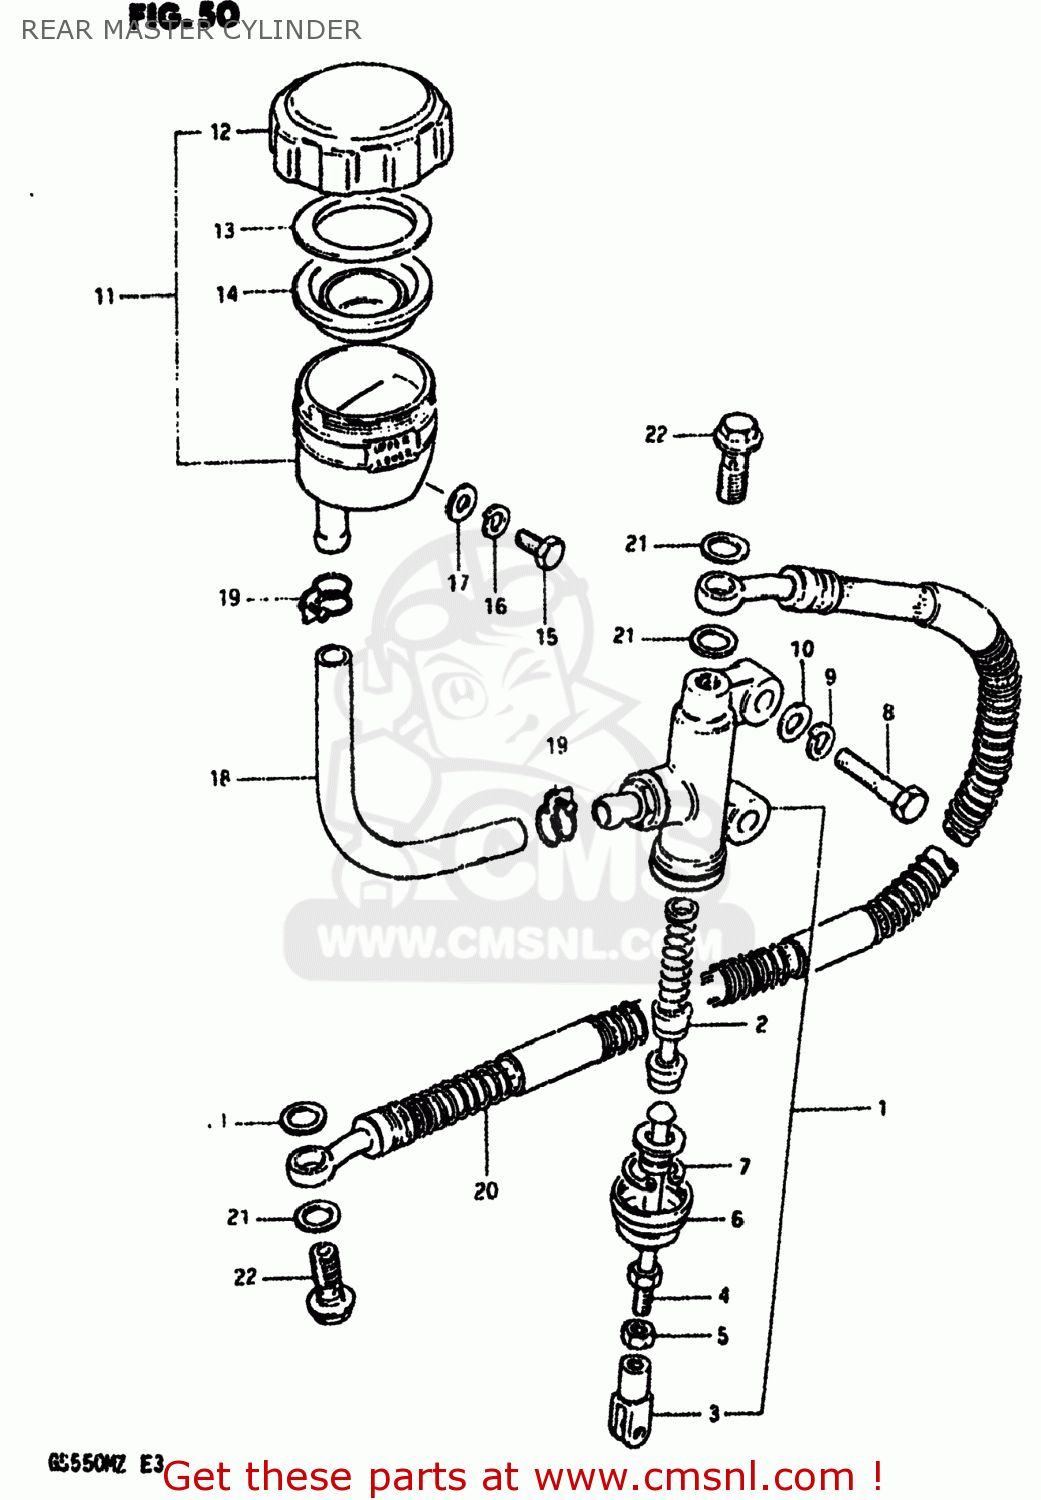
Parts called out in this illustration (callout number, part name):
1	CYLINDER ASSY,RR MASTER
2	PISTON/CUP SET
3	YOKE
4	ROD,REAR MASTER CYLINDER
5	NUT,MASTER CYLINDER
6	BOOT
7	CIRCLIP
8	BOLT (8X30)
9	LOCK WASHER
10	WASHER
11	TANK ASSEMBLY,RESERVOIR
12	CAP
13	PLATE,DIAPHRAGM
14	DIAPHRAGM
15	BOLT, UPPER
16	LOCK WASHER
17	WASHER
18	HOSE,RESERVOIR TANK
19	CLAMP
20	HOSE,REAR BRAKE
21	WASHER
22	BOLT,UNION
